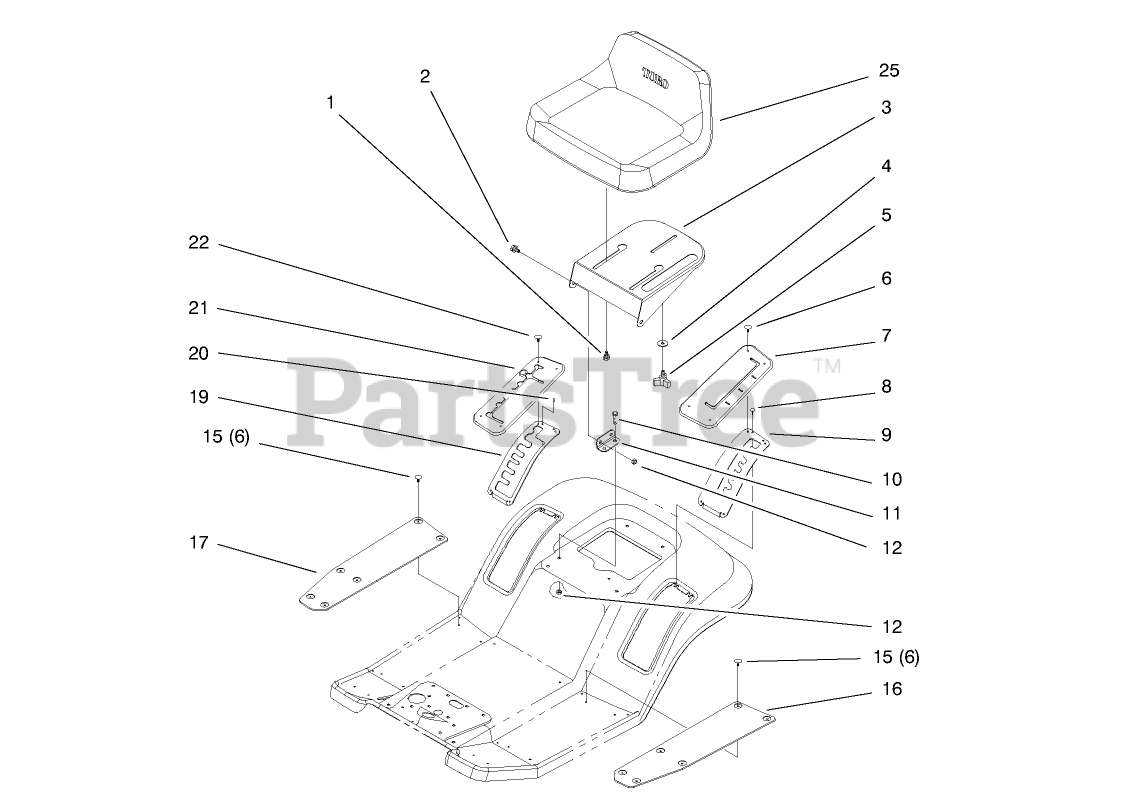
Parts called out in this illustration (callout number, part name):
1	BOLT-SHOULDER
2	BOLT-SHOULDER
3	SEAT SUPPORT
4	WASHER-PIVOT
6	FASTENER-PANEL
7	COVER-HOC
8	RIVET-BLIND
9	GATE-HOC
10	SCREW-HH
11	BRACKET-PIVOT, SEAT
12	NUT-LOCK, NI
15	FASTENER-PANEL
16	MAT-FOOT, LH
17	MAT-FOOT, RH
19	PLATE-GATE, SHIFT
20	RIVET-BLIND
21	COVER-GATE, SHIFT
22	FASTENER-PANEL
